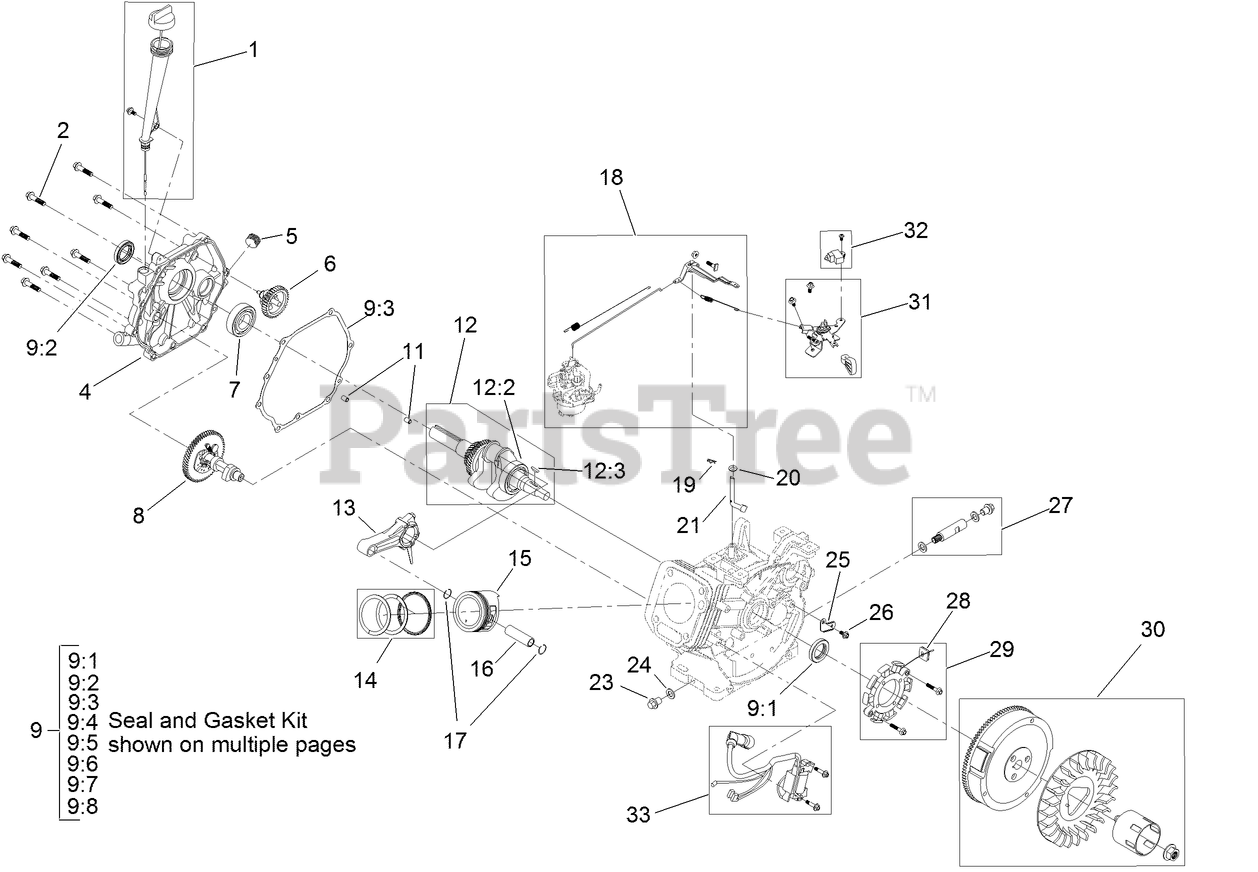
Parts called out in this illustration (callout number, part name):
1	OIL FILL KIT
2	SCREW-HHF
4	COVER-CRANKCASE
5	PLUG-DRAIN
6	GOVERNOR GEAR ASM
7	BEARING-MAIN
8	CAMSHAFT ASM
9	SEAL AND GASKET KIT
9:1	SEAL-OIL
9:2	SEAL-OIL
9:3	GASKET-COVER, CRANKCASE
9:4	GASKET-HEAD, CYLINDER
9:5	GASKET-COVER, VALVE
9:6	GASKET-EXHAUST
9:7	GASKET-CARBURETOR
9:8	GASKET-CARBURETOR
11	PIN-DOWEL
12	CRANKSHAFT ASM
12:2	BEARING-MAIN
12:3	KEY-WOODRUFF
13	CONNECTING ROD ASM
14	SET-RING, PISTON
15	PISTON
16	PIN-PISTON
17	CLIP-PIN, PISTON
18	COMPLETE GOVERNOR KIT
19	PIN-HAIR
20	WASHER-PLAIN
21	SHAFT-GOVERNOR
23	SCREW-HHF
24	WASHER-PLAIN
26	SCREW-HHF
27	DRAIN PLUG KIT
28	GROMMET-RUBBER
29	STATOR KIT
30	FAN AND FLYWHEEL KIT
31	THROTTLE CONTROL KIT
32	KILL SWITCH KIT
